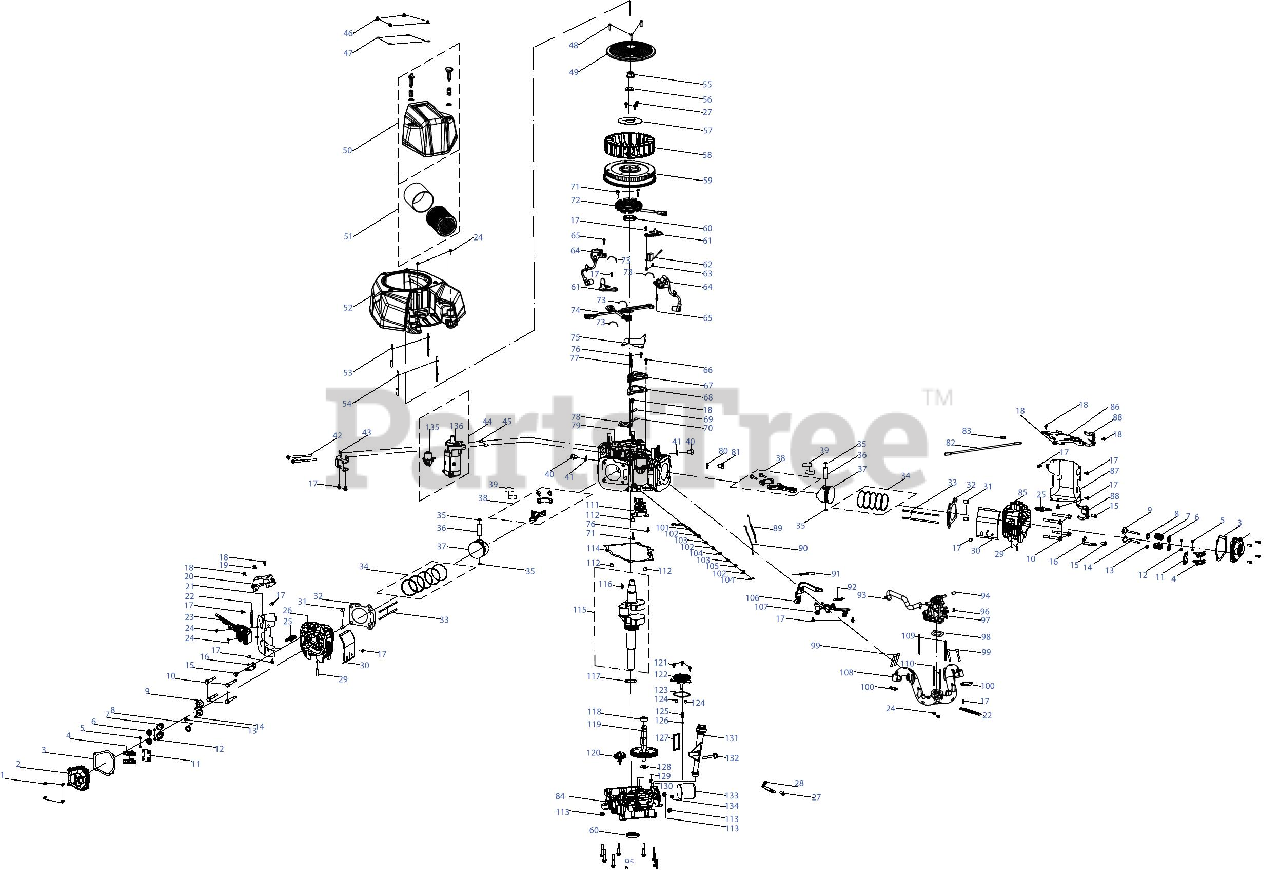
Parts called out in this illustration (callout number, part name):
1	Bolt, M6x22
2	Valve Cover
3	Gasket, Valve Cover
4	Rocker Arm Assembly
5	Valve Adjust Cap, Exhaust
6	Valve Spring Seat
7	Valve Spring
8	Valve Spring Seat
9	Intake Vavle
10	Bolt, M10x1.25x87
11	Rocker Arm Base
12	Valve Locker
13	Intake Valve Seal
14	Exhaust Valve
15	Bolt, M8x16
16	Lift Hook
17	Bolt, M6x12
18	Bolt, M6x10
19	Bolt, M6x10
20	Guard, Right
21	Cylinder Head Baffle
23	Regulator
24	Nut, M6
25	Spark Plug
26	Cylinder Head
27	Bolt, M8x20
28	Lift Hook
29	Stud, M8x34
30	Shroud
31	Pin, 12x20
32	Gasket, Cylinder Head
33	Push Rod
34	Piston Ring Set
35	Circlip
36	Piston Pin
37	Piston
38	Connecting Rod Assembly
39	Connecting Rod Bearing
40	Earth Bolt
41	Washer, 14x1.5x22
42	Bolt, M8x110
43	Starter Relay Support
44	Electric Starter
45	Pin,10x12
46	Nut, M6
47	Washer
48	Self-tappling Screw, ST5.5x25
49	Shroud
50	Air Filter Cover Assembly
51	Air Filter Element
52	Blower Housing
55	Nut, M20x1.5
56	Washer, 20.5x5x40
57	Cooling Fan Plate
58	Cooling Fan
59	Flywheel
60	Oil Seal, 38x58x8
61	he Trigger Support
62	Trigger
63	Bolt, M5x12
64	Ignition Module
65	Bolt, M5x20
66	Bolt, M6x22
67	Breather Cover
68	Gasket, Breather Cover
69	Oil Block
70	Breather Valve
71	Bolt, M6x25
72	Charging Coil
73	Tape, L=150mm
74	Wire Harness
75	Wire Harness Bracket
76	Bolt, M6x16
77	Bolt, M6x28
78	Breather Filter Screen
79	Crankcase
80	Washer, 10.5x1.5x18
81	Bolt, M10x1x10
82	Temperature Sensor
83	Temperature Sensor Clip
84	Crankcase Cover
85	Cylinder Head
86	Shroud, Left
87	Cylinder Head Baffle
88	Fuel pipe bracket
89	Idle Spring
90	Throttle Linkage
91	Governor Spring
92	Governor Spring
93	Breather Hose
94	Intake Manifold Jacket
95	Bolt, M8x48
96	Throttle Linkage Lock Clamp
97	Fuel Sprayer
98	Gasket, Injector
99	Bolt, M8x50
100	Gasket, Intake Manifold
101	Governor Gear Shaft
102	Washer, 8.5x2x15.8
103	Bearing, HK081210
104	Cotter Pin
105	Oil Seal, 8x14x4
106	Governor Lever
107	Governor Gear Bracket Assembly
108	Intake Manifold
109	Stud, M6x35
110	Stud, M6x46
111	Lower Rocker Arm
112	Pin, 8x12
113	Earth Bolt
114	Gasket, Crankcase
115	Crankshaft
116	Woodruff Key
117	Washer, 38.5x1x54
118	Bearing, 6003
119	Camshaft
120	Governor Gear
121	Bolt, M6x18
122	Oil Pump
123	Gasket, Oil Pump
124	Pin, 8x8
125	Oil Pump Spring
126	Steel Ball, 9.5
127	Filter Screw
128	Washer, 17.4x1x25.9
129	O-Ring, 13.2x2.65
130	Pin, 14x10x12.5
131	Dipstick
132	Bolt, M6x55
133	Oil Filter
134	Connection Pipe
135	Starter Relay
136	Electric Starter
